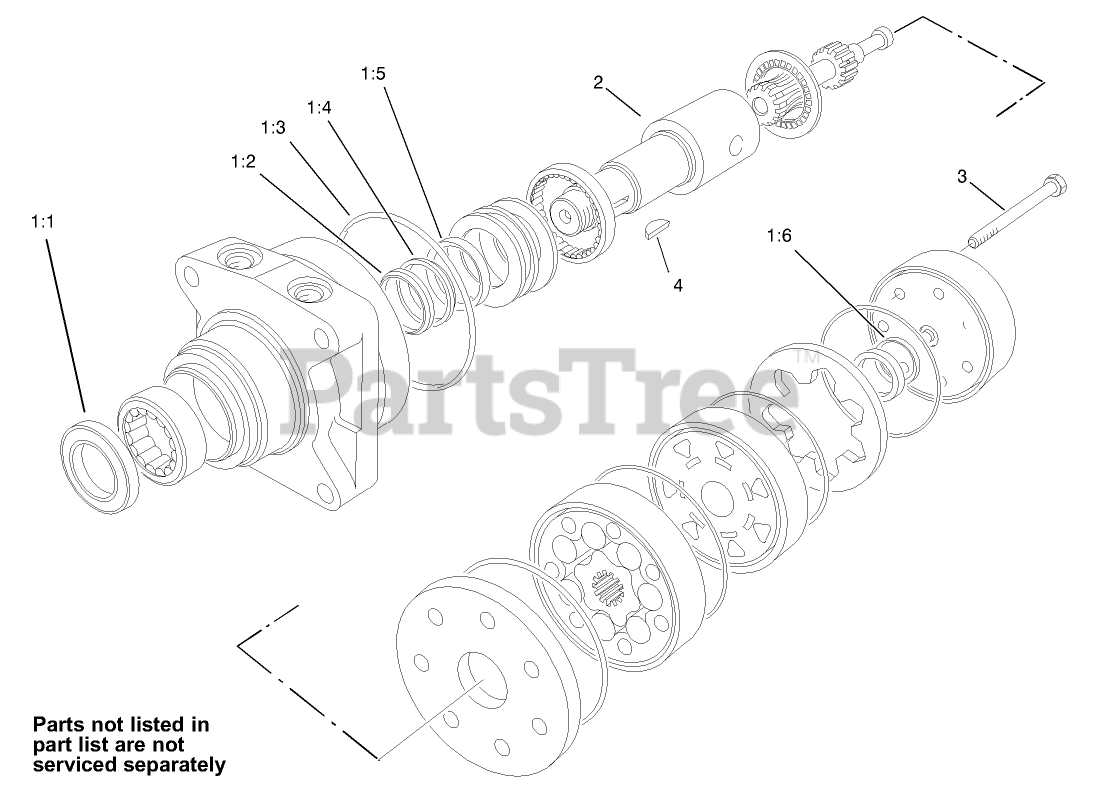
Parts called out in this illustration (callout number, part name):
1	SEAL KIT
1:1	SEAL-DIRT AND WATER
1:2	Washer-Backup
1:3	Seal-Ring
1:4	Washer-Backup
1:5	Seal-Inner
1:6	Seal-Commutator
2	SHAFT-COUPLING
3	SCREW-CAP, HH
4	KEY-WOODRUFF
